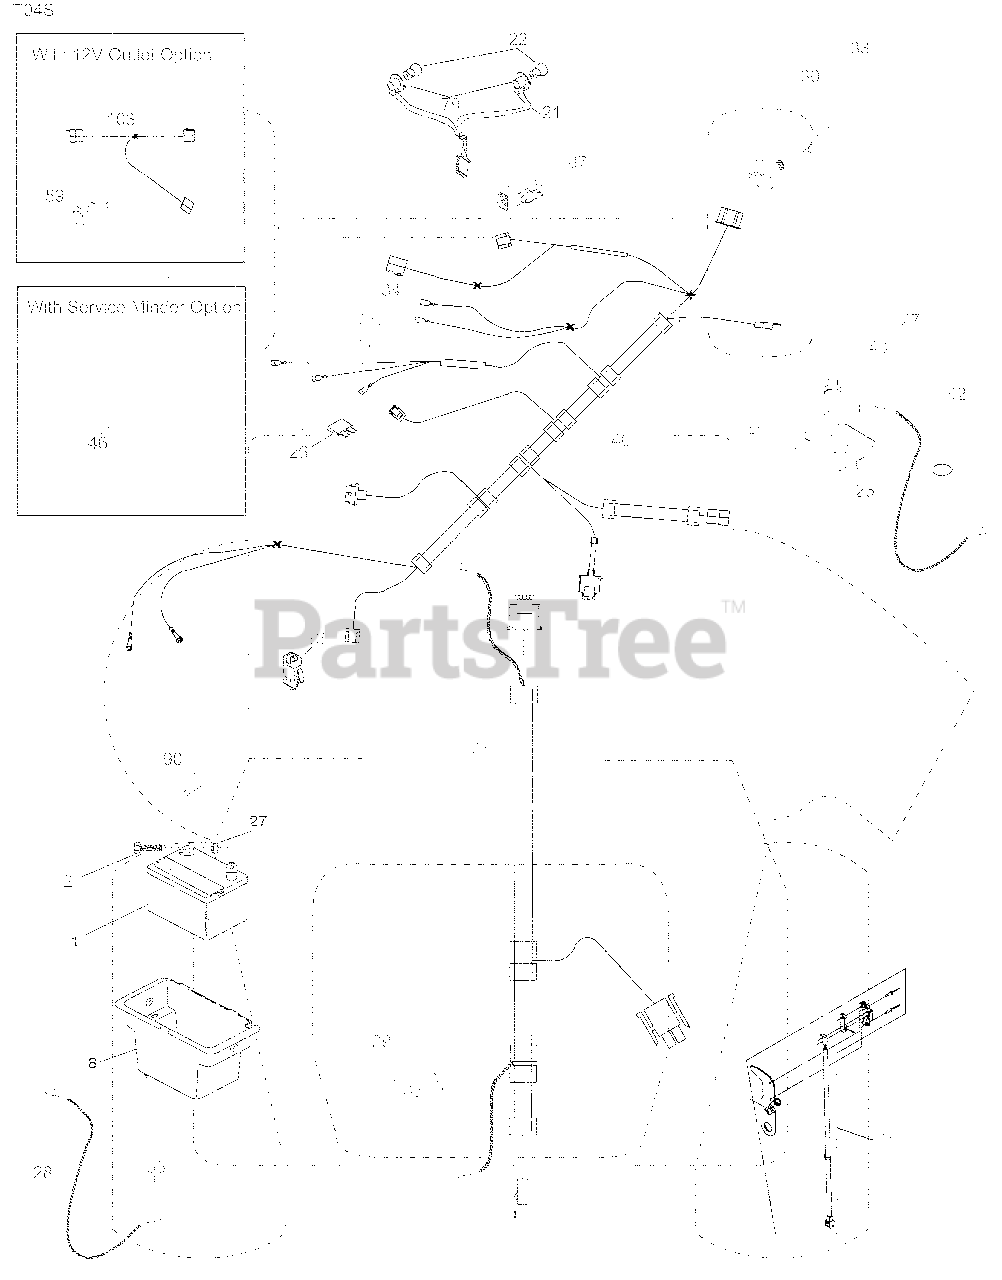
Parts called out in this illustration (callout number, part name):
1	Battery
2	Bolt Hex Head 1/4-20 x 3/4
8	Box Battery
16	Switch Interlock Push-In
21	Harness Socket Light W/4152J
22	Bulb Light
25	Cable Starter
27	Nut Keps Hex 1/4-20 unc
28	Cable, Ground
29	Switch, Seat
30	Switch, Ign
33	Key/Chain
34	Switch Light / Reset
40	Harness Ign. Dash
41	Screw Thd Cut 1/4-20 x 1/2
42	Cover, Terminal
43	Solenoid
46	Gauge Servicereminder Hrmtr
55	Screw Thdrol 5/16-18 x 3/4 TYTT
71	Harness Ign.
79	Socket Asm. Bulb
90	Cover Terminal
141	Kit T2 ROS
